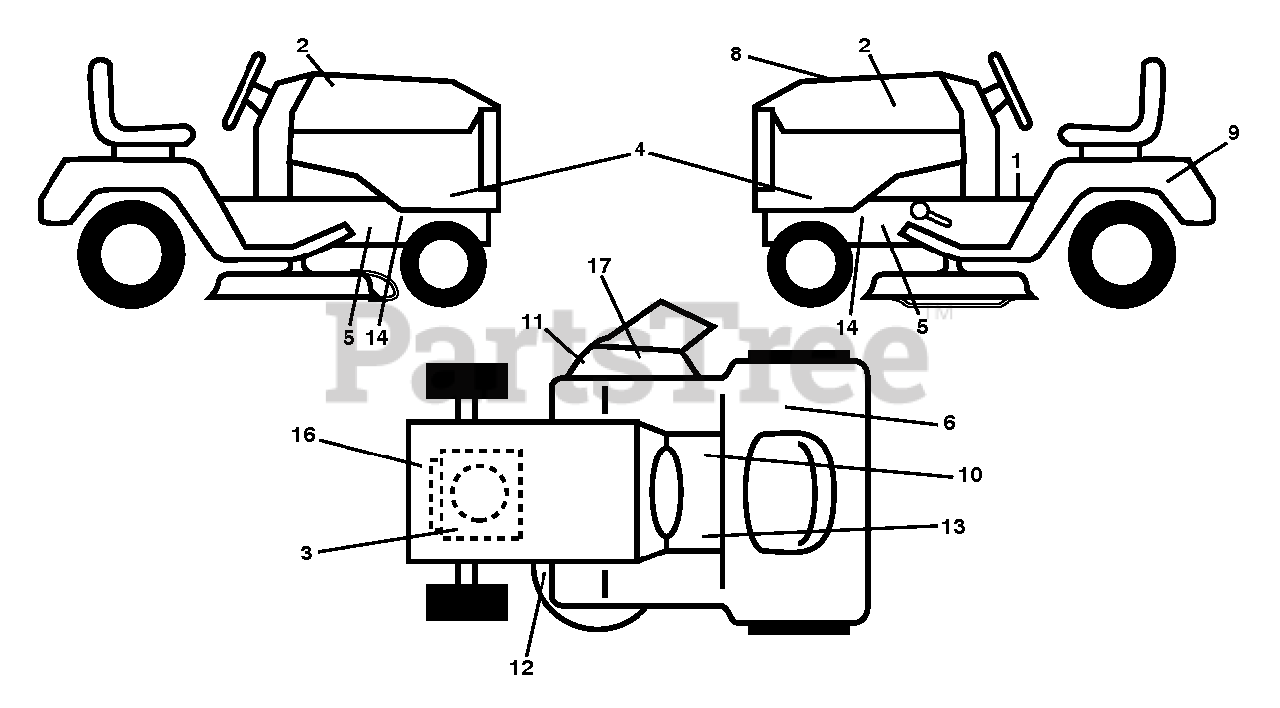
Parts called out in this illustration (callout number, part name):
1	DECAL.READ.OWN.MAN.SYMBOL.LT
2	DECAL.BADGE.170MM.TEXTLOGO.
3	DECAL.ENGINE.WARNING
4	DECAL.SDPNL.TS38
5	DECAL.CHASSIS.HOT.MUFFLER
6	Decal, Certification 6MIL 100D
8	DECAL.RPL.BSM21.PB.TLW.38.PMST
9	DECAL BTRY SYMBOLS
10	DECAL.PARKING.BRAKE.SADDLE.LT
11	DECAL.DFLCTR.WARNNG.CTFNGR.SYM
12	DECAL.DECK.SCH.36,38,94.NONCR
13	DECAL.FNDR.SDLE.BRAKE.CLUTCH.6
14	DECAL.WARNING.SERVCE/FIRE
16	DECAL.ENG.BS.3125SER.PB.279738
17	DECAL, DECK DEFLECTOR, WARNING
